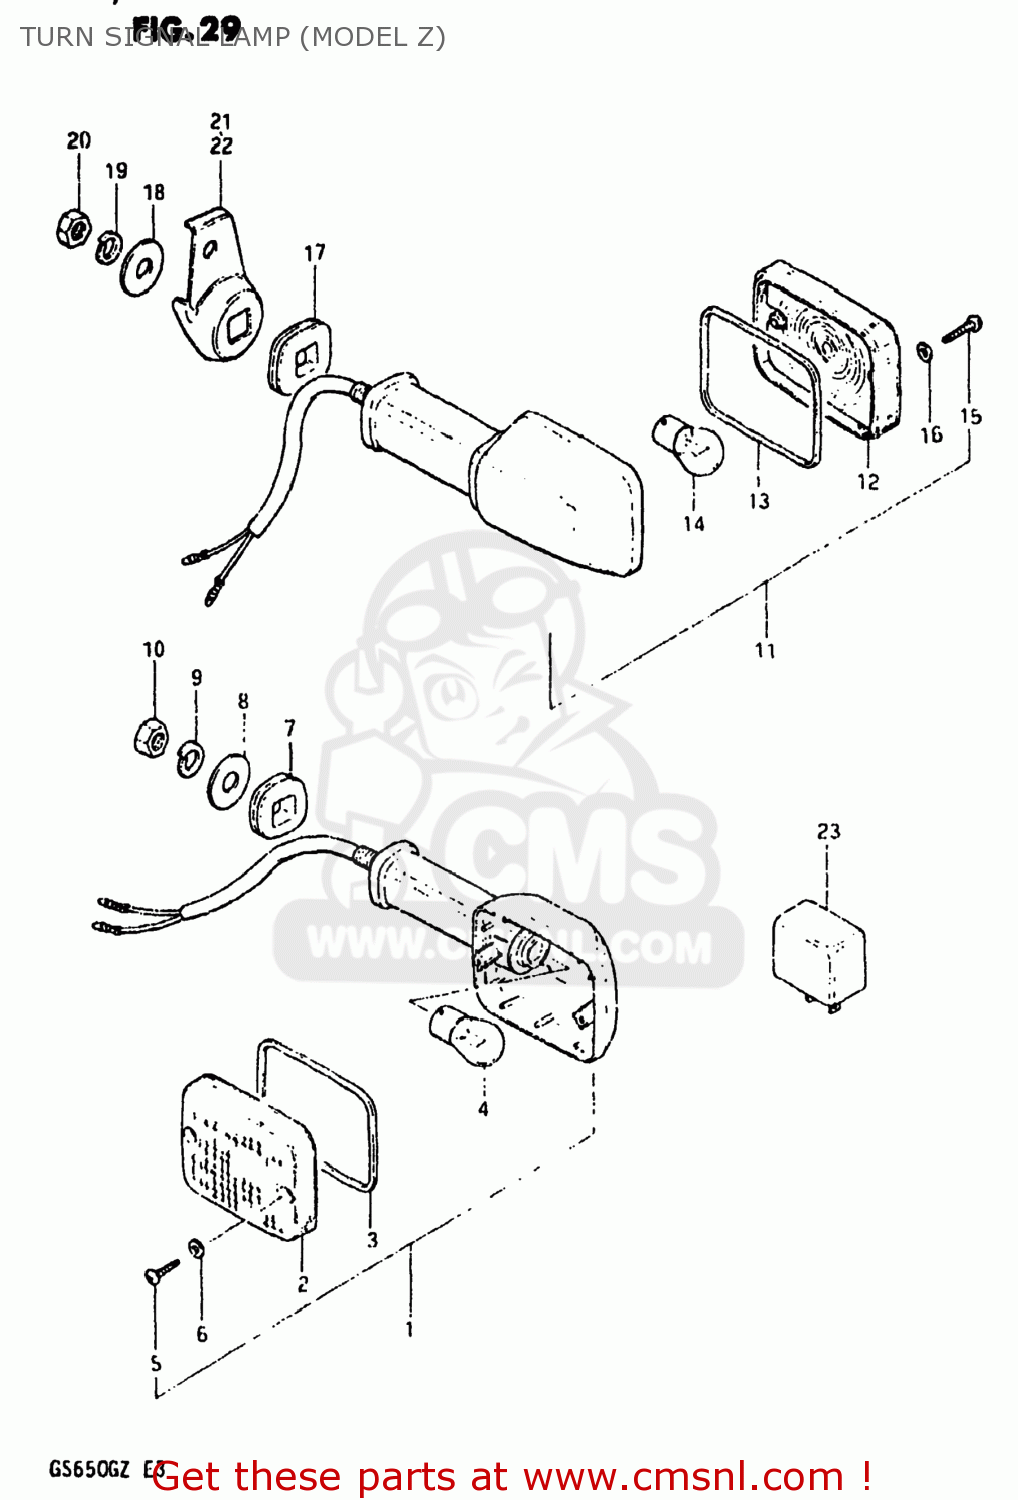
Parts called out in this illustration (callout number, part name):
1	LAMP ASSEMBLY,FRONT TURN SIGNAL
2	LENS
3	GASKET (NAS)
4	BULB(12V23W,STANLEY,A4577A)
5	SCREW
6	GASKET (NAS)
7	CUSHION
8	WASHER (10.5X30X2.3)
9	LOCK WASHER
10	NUT
11	LAMP ASSEMBLY,FRONT TURN SIGNAL
12	LENS
13	GASKET (NAS)
14	BULB(12V23W,STANLEY,A4577A)
15	SCREW
16	GASKET (NAS)
17	CUSHION
18	WASHER (10.5X30X2.3)
19	LOCK WASHER
20	NUT
21	BRACKET,REAR TURN SIGNAL
22	BRACKET,REAR TURN SIGNAL
23	RELAY,TURN SIGNAL
